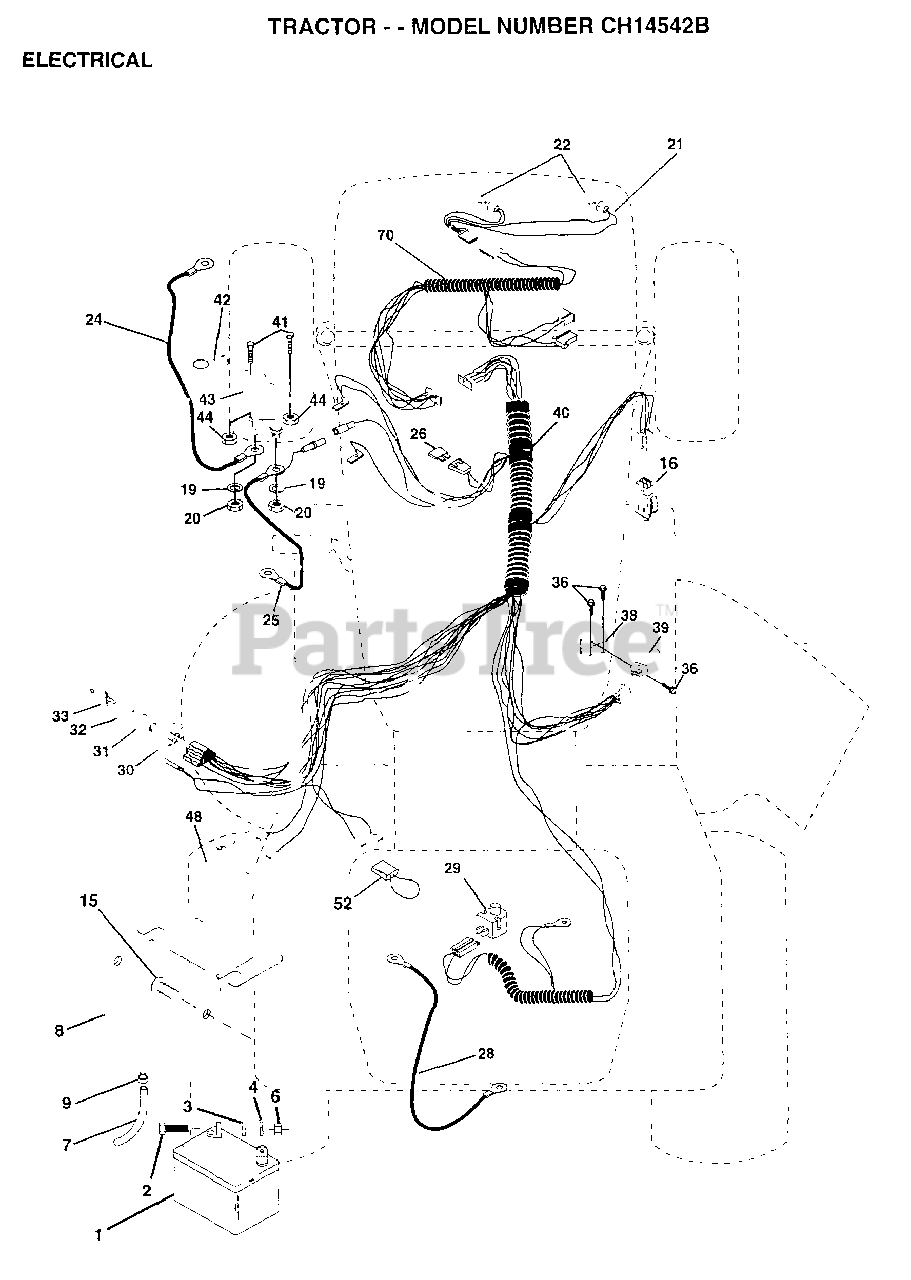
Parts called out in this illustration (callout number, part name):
2	BOLT LT
3	WASHER
4	LOCKWASHER
7	TUBE T
9	HOSE CLAMP T
15	FASTNER.SNAP-IN
16	SWITCH INTERLOCK
20	NUT
21	"HARNESS,LIGHT SOC"
22	HEADLAMP BULB
24	"CABLE T, BATTERY"
25	CABLE.BTRY.6GA.RD
26	FUSE HYT
28	CABLE T
29	SWITCH SEAT
30	SWITCH IGN 4POS
31	NUT IGNITION
32	COVER KEY SWITCH
33	KEY
36	SCREW
38	BRACKET SWITCH IN
39	SWITCH INTERLOCKT
40	HARNESS.IGNITION
41	BOLT HXHD FIN
44	NUT HXKEP 1/4X20
48	ADAPTER AMMETER
52	PROTECTION LOOP
70	HARNESS ENGINE
